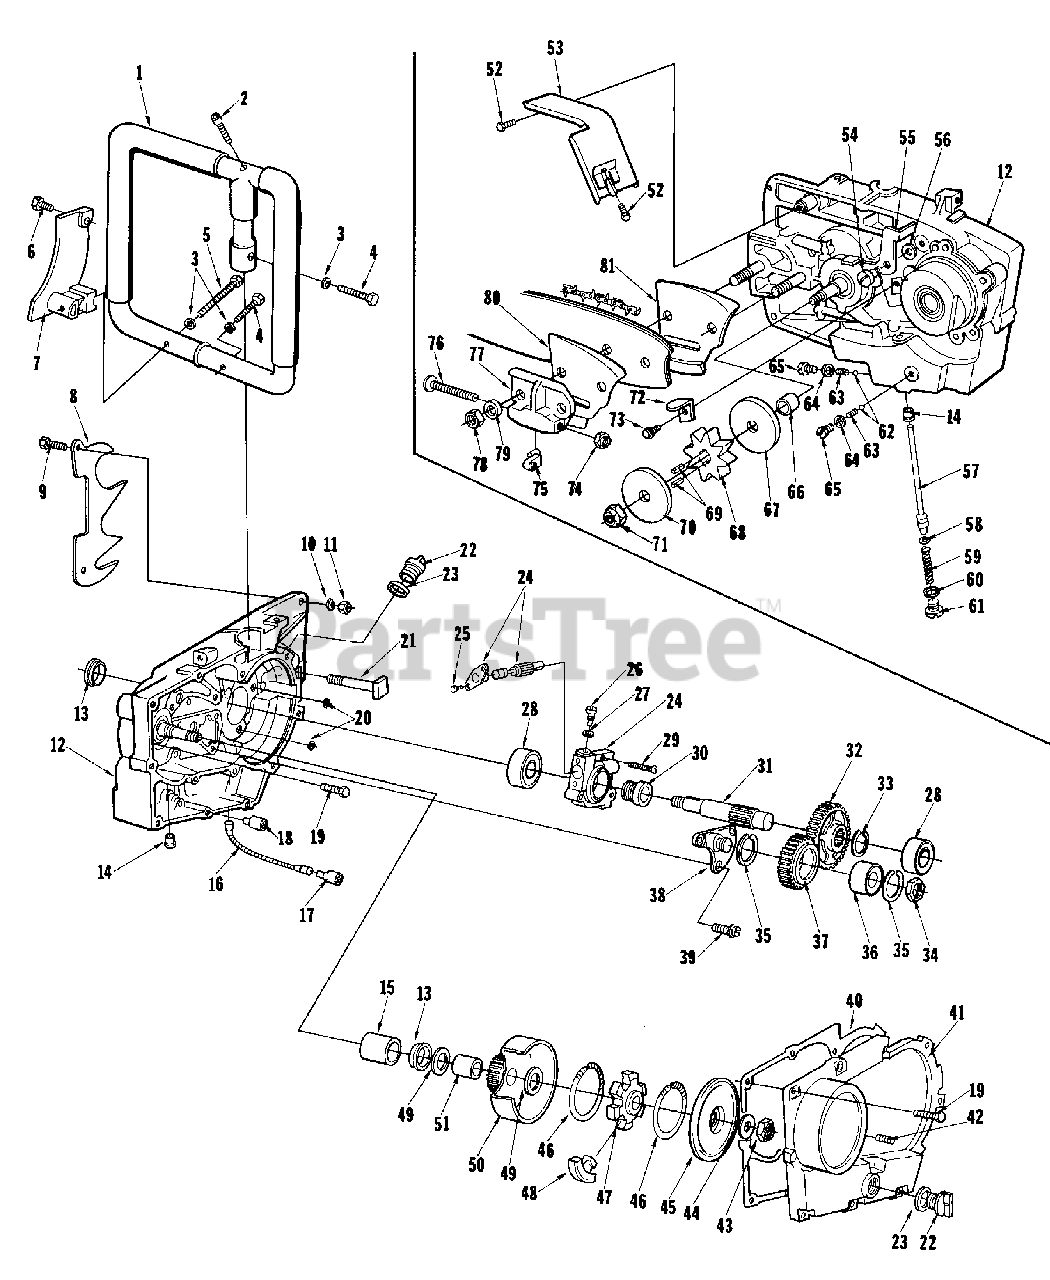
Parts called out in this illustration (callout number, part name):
1	HANDLE BAR
2	SCREW- Soc, 5/16-18 x 1
3	WASHER- Lock, 5/16
4	SCREW- Hex, 5/16-18 x 1-1/2
5	SCREW- Hex, 5/16-18 x 3-1/4
6	SCREW- Hex, 12-24 x 7/8
7	BRACKET- Handle bar
8	KIT- Spiked bumper (long spikes)
9	SCREW- Hex, 1/4-20 x 7/8
10	WASHER- Lock, 1/4
11	NUT- 1/4-20
12	HOUSING- Gear
14	BUSHING- Rod
15	BEARING
16	LINE- Oil
17	FILTER- Oil (automatic)
18	FILTER- Oil (manual)
19	SCREW- Hex, 12-24 x 3/4
20	"O" RING
21	BOLT- Guide bar
22	CAP- Filler (oil)
24	PUMP- Automatic oil
25	SCREW- Pan, 4-40 x 1/4
26	SCREW- Cam
28	BEARING- Ball
29	SCREW- Hex, 8-32 x 7/8
30	WORM- Gear
31	SHAFT- Sprocket
32	GEAR- Driven; 3:1 ratio, 64 teeth
33	RING- Retaining
34	NUT- Idler gear
35	RING- Retaining
36	BEARING- Ball
37	GEAR- Idler
38	POST- Idler gear
39	SCREW- Hex, 1/4-20 x 3/4
41	COVER- Gear housing
42	PLUG- Pipe
43	NUT- Hex, 3/8-24
45	COVER- Clutch
46	SPRING- Clutch
47	SPIDER- Clutch
48	SHOE- Clutch
49	WASHER- Thrust
50	DRUM- Clutch w/gear
51	BEARING- Sleeve
52	SCREW- Hex, 12-24 x 3/8
53	GUARD- Chain
54	SCREW- Pivot
55	BELL CRANK
56	WASHER- Thrust
57	PLUNGER- Oil pump
58	"O" RING
59	SPRING- Compression
61	CAP- Oil pump
62	BALL- Check
63	SPRING- Check valve
64	GASKET- Check valve cap
65	CAP- Check valve
66	SPACER- Sprocket
67	WASHER- Sprocket (inner)
68	SPROCKET- 1/2" pitch, 8 tooth
69	KEY- Sprocket
70	WASHER- Sprocket (outer)
71	NUT- Hex, 1/2-20
72	BRACKET- Rod
73	SCREW- Hex, 10-24 x 3/8
74	NUT- Hex lock
75	PIN- Guide bar adjusting
76	SCREW- Rd, 5/16-18 x 2-1/8
78	NUT- Hex, 3/8-16
79	WASHER- Lock, 3/8
80	PLATE- Guide bar (outer)
81	PLATE- Guide bar (inner)
